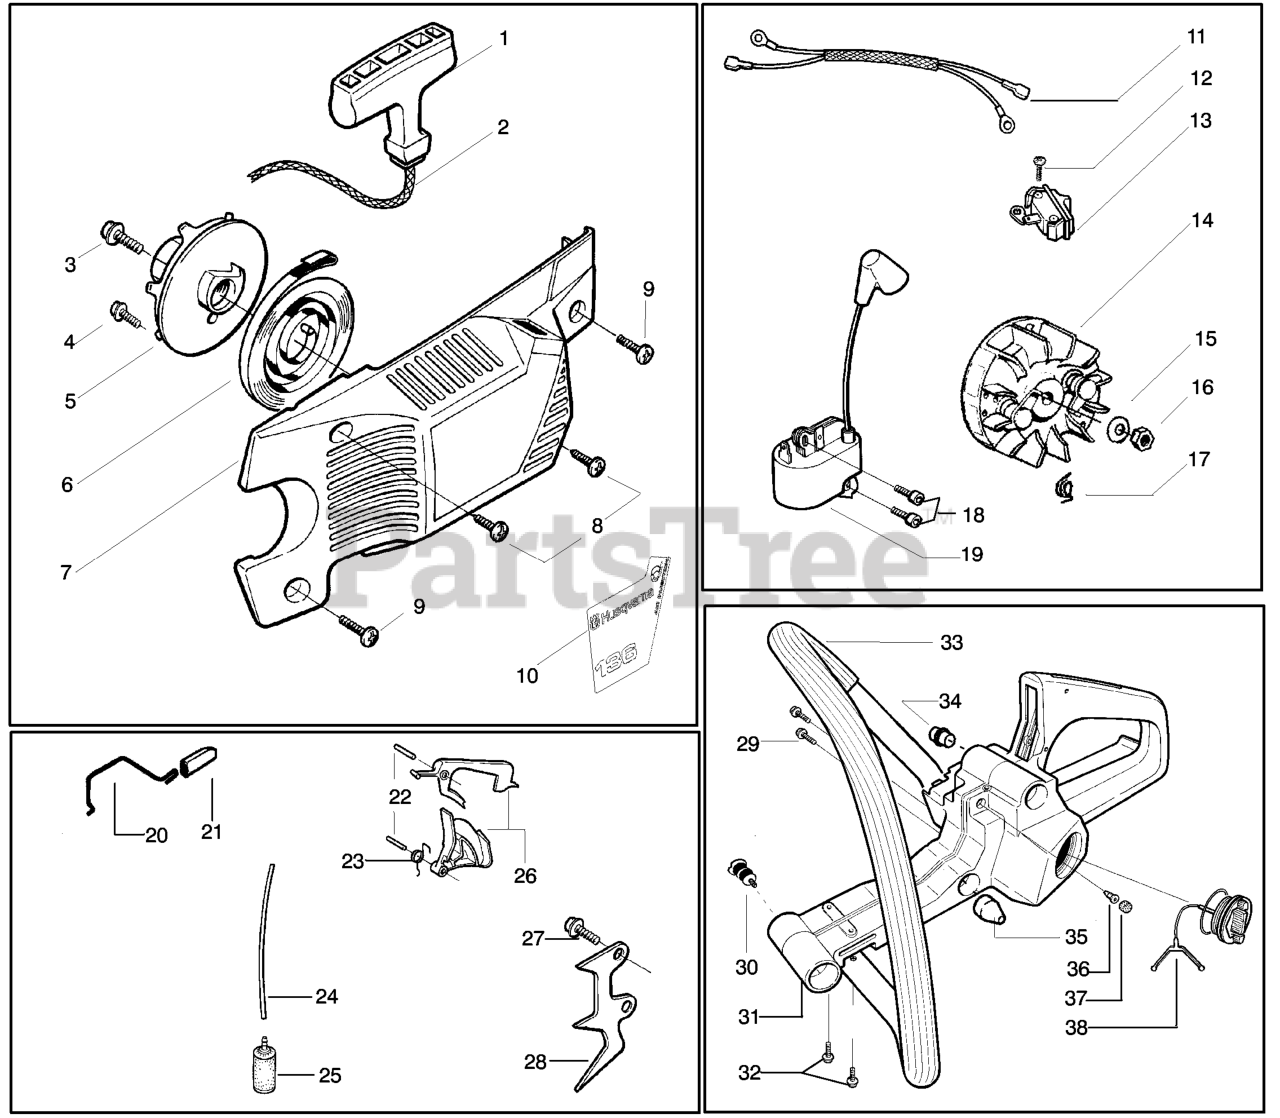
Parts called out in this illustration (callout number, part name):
1	STARTER HANDLE
5	PULLEY 36/41
6	RETURN SPRING
7	FAN HOUSING ASSEMBLY
8	SCREW,STRTR CVR 36/41
10	Decal -Model
11	LEAD WIRE ASSY
13	SWITCH ON/OFF
14	ROTOR COMPL. 36/41
15	WASHER-FLYWHEEL
17	SPRING STR DOG
18	SCREW,IGN MOD 36/41
19	%IGNITION MODULE
20	THROTTLE SHAFT 36/41
21	THROTTLE ACTUATOR 36/41
22	PIN,TRIGGER 36/41
23	TRIGGER SPRING 36/41
24	HOSE. FUEL
25	FUEL PICK-UP
26	THROTTLE TRIGGER-KIT
27	SCREW-10-14 X 1/2 PLASTITE
28	SPIKE 36/41
33	FRONT HANDLE
34	FRONT HANDLE ISOLATOR
35	SHOCK MOUNT(X2) 36/41
36	VALVE-CHECK (DUCKBILL)
37	BRONZE PLUG
38	FUEL CAP KIT
